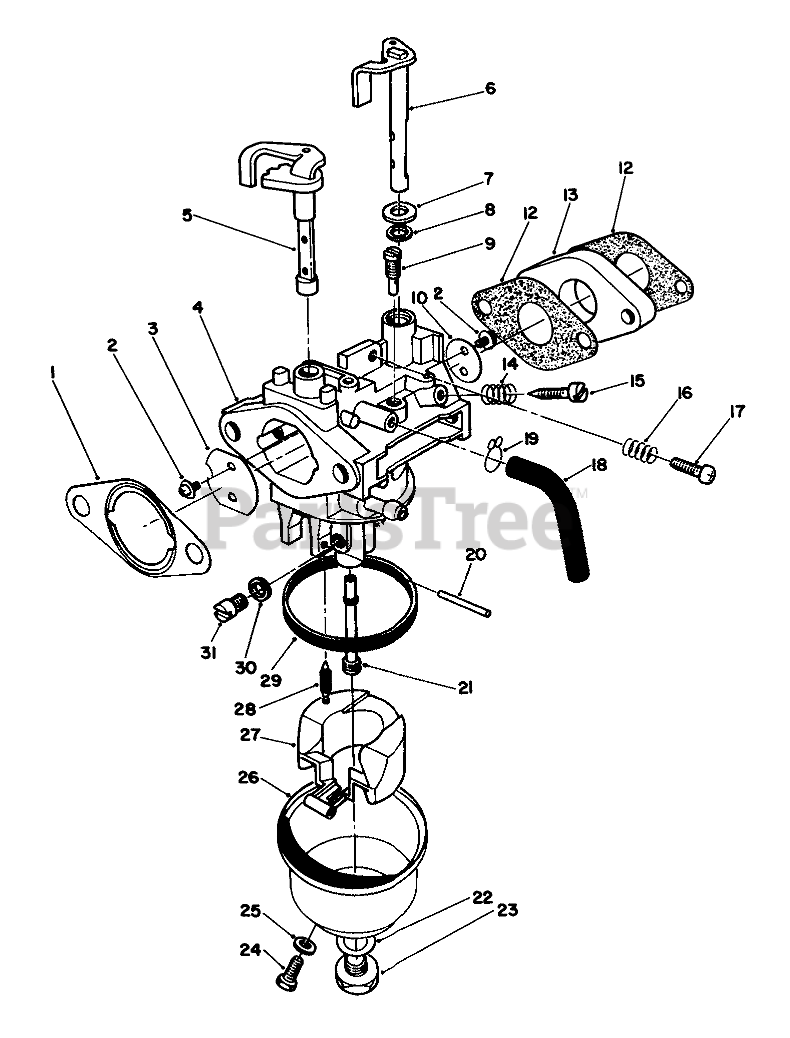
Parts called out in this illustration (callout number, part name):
1	GASKET F/W ENGINE
2	Screw
3	VALVE
4	Carburetor Assembly (Incl. Ref. #2-31)
5	SHAFT
6	SHAFT
7	WASHER
8	Seal-Throttle Shaft
9	PILOT JET
10	VALVE
12	Gasket-Carburetor
13	CARB INSULATOR
14	SPRING-PILOT SCREW
15	ADJUSTER
16	Spring-Idle Stop
17	SCREW
19	CLAMP
20	Pin
21	NOZZLE
22	GASKET
23	SCREW
24	SCREW
25	GASKET
27	Float
28	NEEDLE
29	FLOAT BOWL GASKET
30	SPACER
31	MAIN JET
